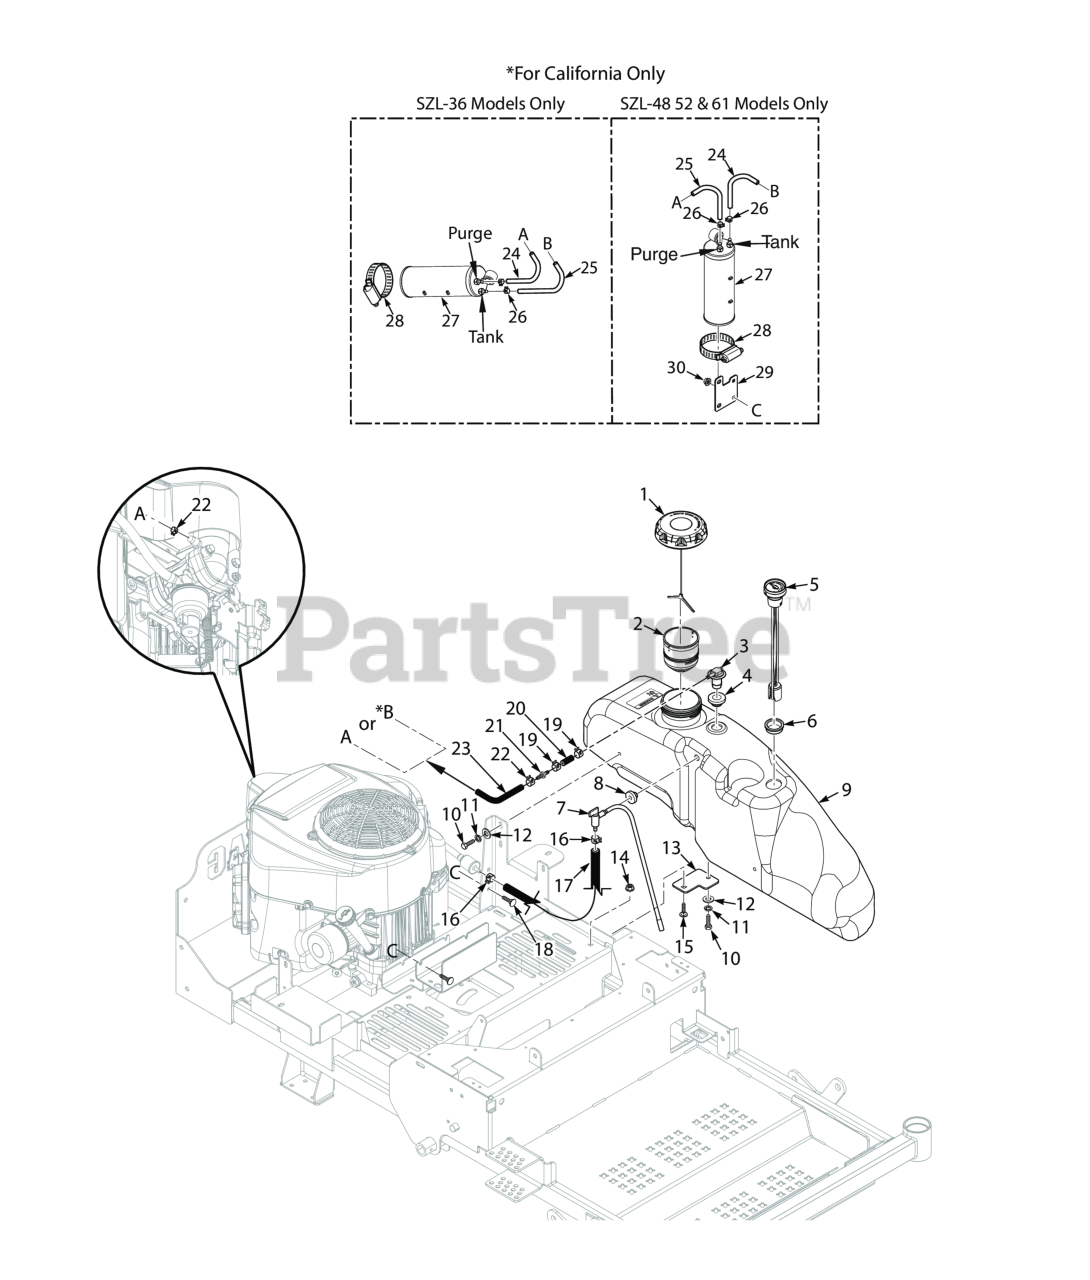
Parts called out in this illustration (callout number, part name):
1	Fuel Cap w/ Tether (E.P.A.)
1	Fuel Cap w/Tethered - California Models Only
2	TUBE, FUEL INLET - 3.00
3	Remote Vent, No Valve
4	Grommet, Viton,
5	Fuel Gauge (requires #6)
6	Grommet, Fuel Gauge
7	Valve, Fuel Shut Off
8	Bushing, 0.56" Dia. Viton
9	Fuel Tank Assembly SZL-36
10	BOLT, SERRATED FLANGE HEX HEAD 5/16-18 X 3/4"
11	Lockwasher, 5/16 (.317 x .586 x .078) Helical Spring
12	Flatwasher, 5/16-.375 x .875 x .083 (35BV & 37BV-EFI)
13	Mounting Bracket, Fuel Tanks Front
14	Nut, Serrated Flange 5/16-18 (Right Front Engine Mounting, Briggs and Kohler Only)
15	Bolt, 5/16-18 x .75 RHSN Carriage
16	Clamp, Fuel Hose 1/4" Hose I.D.
17	Fuel Hose, 1/4" I.D. Non-Perm (791DFI Fuel Return) - Order by Inch
18	Serr. Fl. Hex Head CPSCR, 1/4-20 x 3/4"
19	CLAMP, FUEL HOSE(KAWASAKI ONLY)
20	Hose, 1/4" Vapor Recovery (order by inch)
21	Mender, 1/4 x 3/16 w/0.02 Hole
22	Clamp, Vapor Recovery Hose 3/16"
23	Hose, Vapor Recovery 3/16" (order by inch)
24	Hose, Vapor Recovery 3/16" (order by inch)
25	Hose, Vapor Recovery 3/16" (order by inch)
26	Clamp, Vapor Recovery Hose 3/16"
27	Carbon Canister - SVR-36A / SVR-48V
27	Dust Filter, Carbon Canister
28	Clamp, 3-1/2" Max. Dia.
29	Bracket, Cannister Mount
30	NUT, 1/4-20 SERRATED FLANGE HEX HEAD
